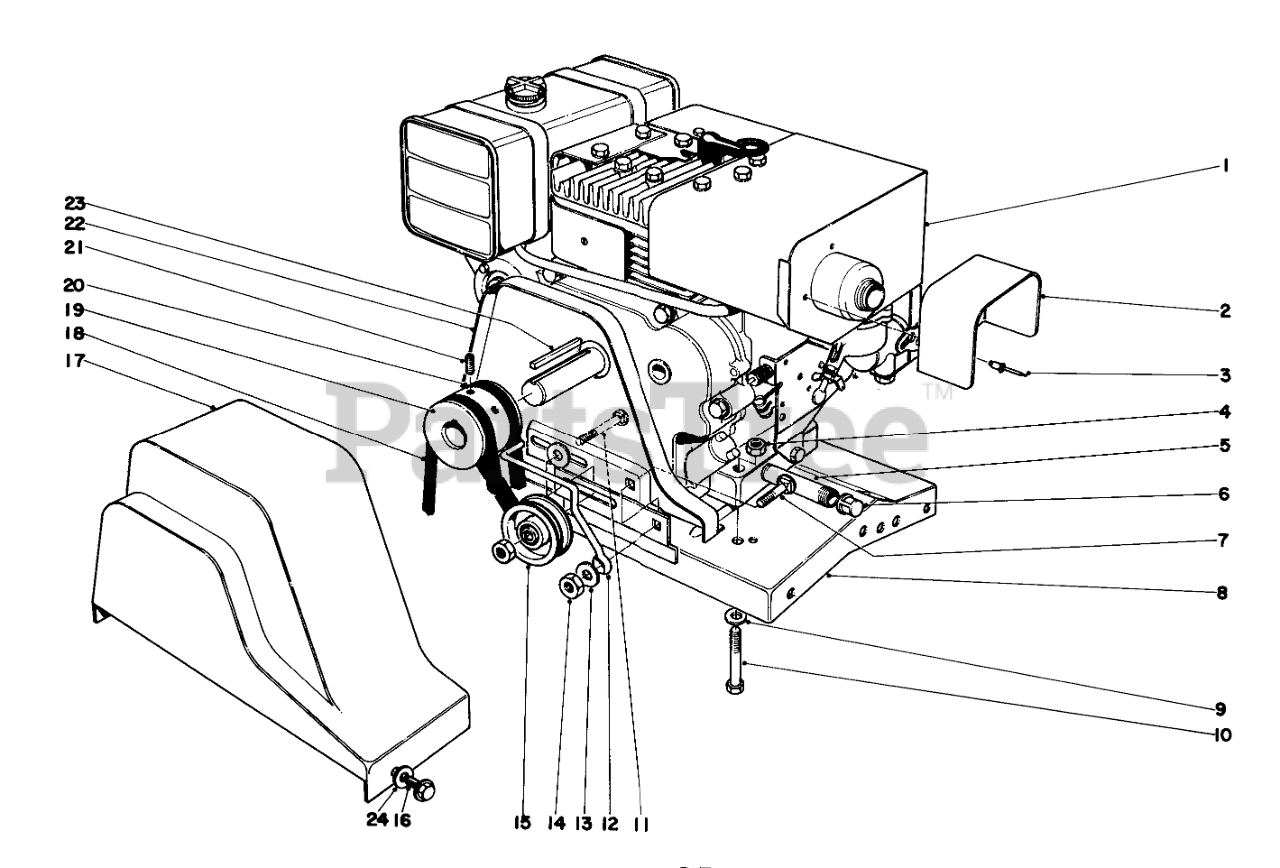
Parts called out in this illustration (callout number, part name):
1	Engine (Recoil)
2	Shield, Muffler
3	.187 X 1/4 POP RIVET
4	Nut
5	NIPPLE-PIPE
6	CAP-PIPE
7	SCREW-CARR
8	Engine Base
9	WASHER-FLAT
10	SCREW-HH
11	SCREW-CARR
12	BELT GUIDE
13	WASHER-FLAT
14	NUT-HEX
15	PULLEY-IDLER
16	1/4-20 X 1/2 SEMS MS
17	Belt Guard
18	V-Belt
19	Engine Pulley
20	V-Belt
21	1/4-20 X 5/8 SETSCREW
22	Belt Guard
24	WASHER-FLAT
